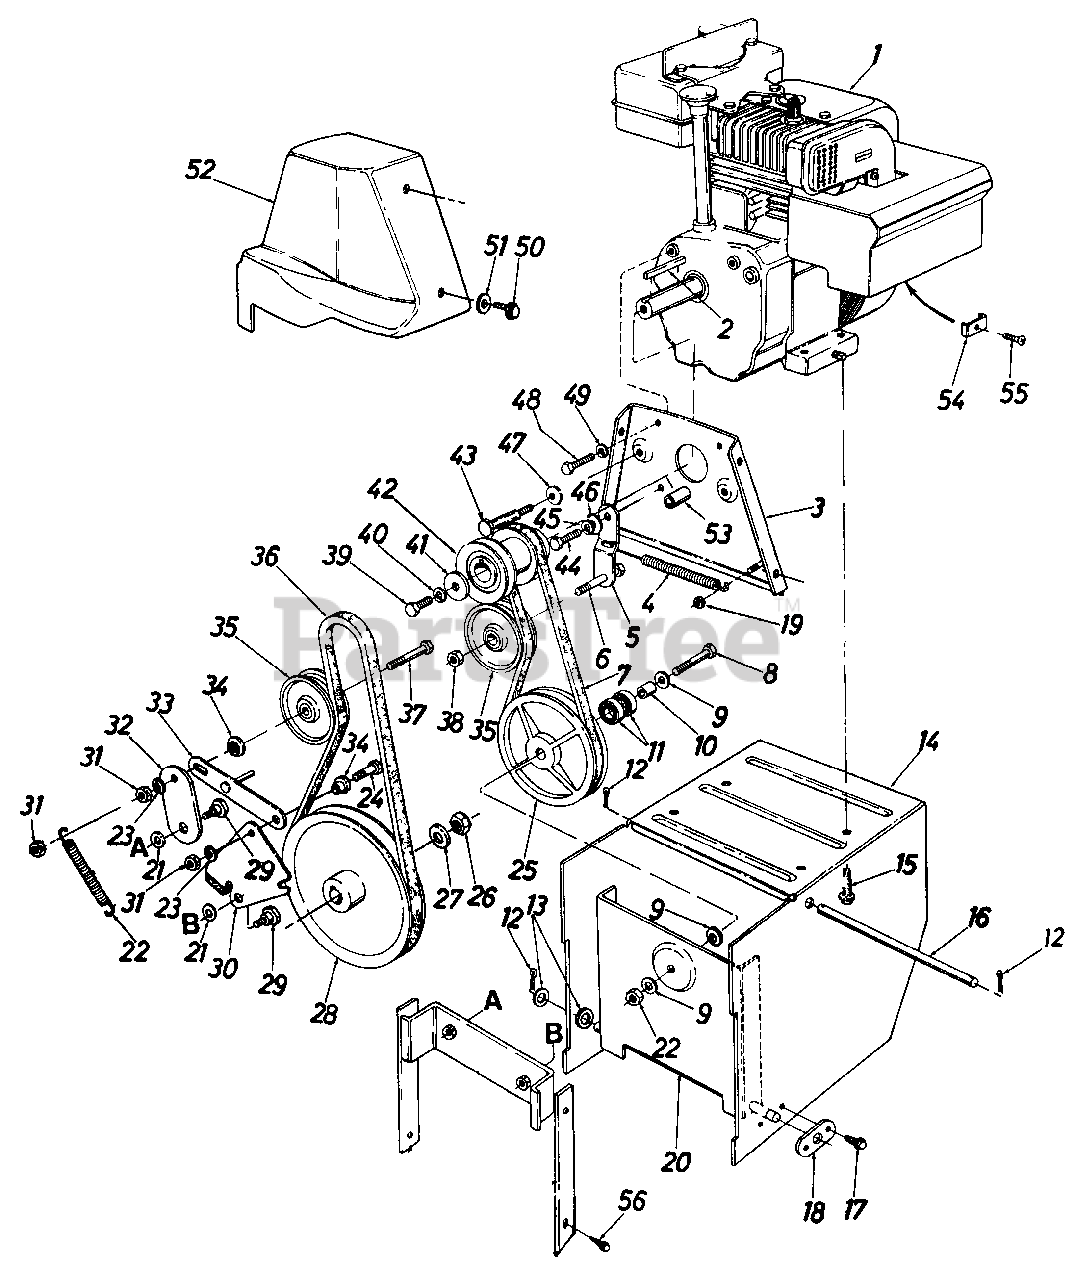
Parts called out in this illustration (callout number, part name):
1	Engine
2	Sq. Key 3/16" x 1.50" Lg.
3	Engine Plate Ass'y.
4	Extension Spring .50" O.D. x 3.97" Lg.
5	Drive Clutch Idler Brkt.
6	Hex Bolt 3/8-24 x 1.25" Lg.*
7	V-Belt 3/8" x 29.0" Lg.
8	Hex Bolt 3/8-24 x 1.50" Lg.*
9	Bell-Wash. .40" I.D. x .88" O.D. x .06
10	Spacer .38" I.D. x .62" O.D. x.75" Lg.
11	Ball Brg. .62" I.D. x 1.38" O.D. x .44
12	Cotter Pin 3/32" Dia. x .75" Lg.*
13	Fl-Wash. .53" I.D. x 1.00" O.D. x.125
14	Frame Ass'y.
15	Hex Wash. Hd. Self-Tap Scr. 318-16 x 1.25" Lg.
16	Shaft .50" Dia. x 9.50" Lg.
17	Hex Wash. Hd. Self-Tap Scr. 1/4-20 x .50" Lg.
18	Axle Bracket
19	Hex L-Nut 1/4-20 Thd.
20	Drive Pulley Support Brkt. Ass'y.
21	Bell-Wash. .40" I.D. x 1.13" O.D.
22	Extension Spring .50" O.D. x 3.97" Lg.
23	L-Wash. 3/8" I.D.*
24	Hex Scr. 3/8-16 x 1.25" Lg.
25	6.00" O.D. Drive Pulley Ass'y.
26	Hex Jam Cent. L-Nut 5/8-18 Thd.
27	Fl-Wash. .64" I.D. x .94" O.D. x .06
28	1/2" V-Pulley .625" I.D. x 7.50" O.D.
29	Shld. Bolt .625" Dia. x .170" Lg. (3/8-16)
30	Brake Bracket Ass'y.
31	Hex Ins. L-Nut 3/8-16 Thd.
32	Auger Clutch Idler Brkt.
33	Brake Linkage Ass'y.
34	Shld. Spacer.625" I.D.
35	Flat Idler 2.25" O.D.
36	V -Belt 3/8" x 38" Lg.
37	Hex Bolt 3/8-16 x 2.25" Lg.*
38	Hex Ins. Jam L-Nut 3/8-24 Thd.
39	Hex Bolt 3/8-24 x 1.50" Lg.
40	L-Wash. 3/8" I.D.
41	Fl-Wash. .40" I.D. x 1.25" O.D.
42	Double Groove Engine Pulley
43	Shld. Scr. .498" x 3.0" Lg.
44	Hex Bolt 5/16-24 x 1.00" Lg.*
45	L-Wash. 5/16" I.D.
46	Shld. Spacer.320" I.D.
47	Bell-Wash. .40" I.D. x .88" x .06
48	Hex Bolt 5/16-24 x .62" Lg.
49	L-Wash. 5/16" I.D.
50	Hex Wash. Hd. Self-Tap Scr. 1/4-20 x .50" Lg.
51	Fl-Wash. .28" I.D. x .75" O.D. x .06
52	Belt Cover
53	Spacer
54	Throttle Control Wire Clamp
55	Hex Sems Scr. #10-32 x .62" Lg.
56	Hex Wash. Hd. Self-Tap Scr. 3/8-16 x .75" Lg.
